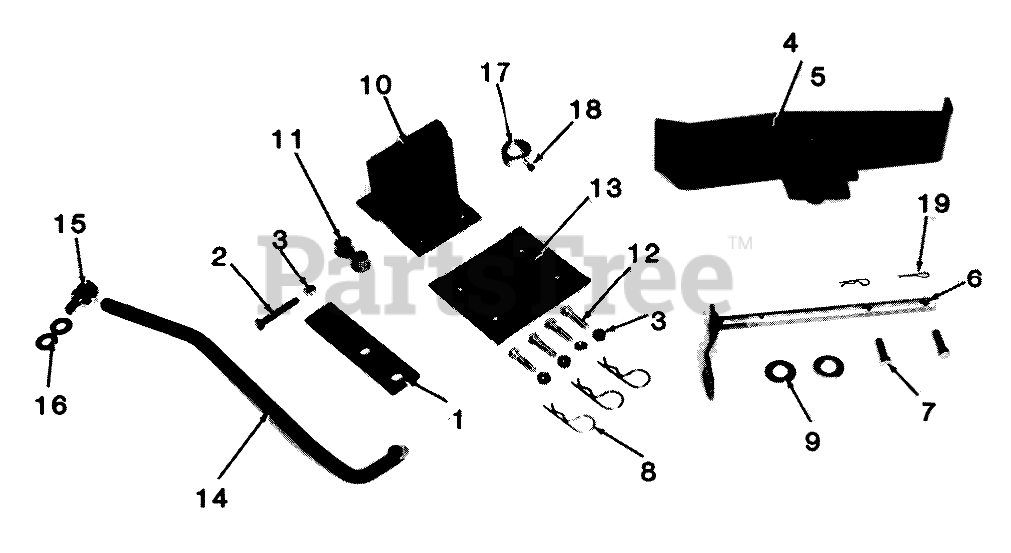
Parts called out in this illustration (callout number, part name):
1	BAR - CONTROL R
2	Screw-Hex. Hd.
3	Nut
4	Pedal
5	PAD PEDAL
6	Pivot Rod
7	Locking Pin
8	Hairpin Cotter
9	Washer
10	Pedal Support
11	BUSHING
12	Bolt
13	Backup Plate
14	Bellcrank Rod
15	STUD-TRUNION
16	Washer
17	Collar
18	SCREW-SET
19	Hairpin
